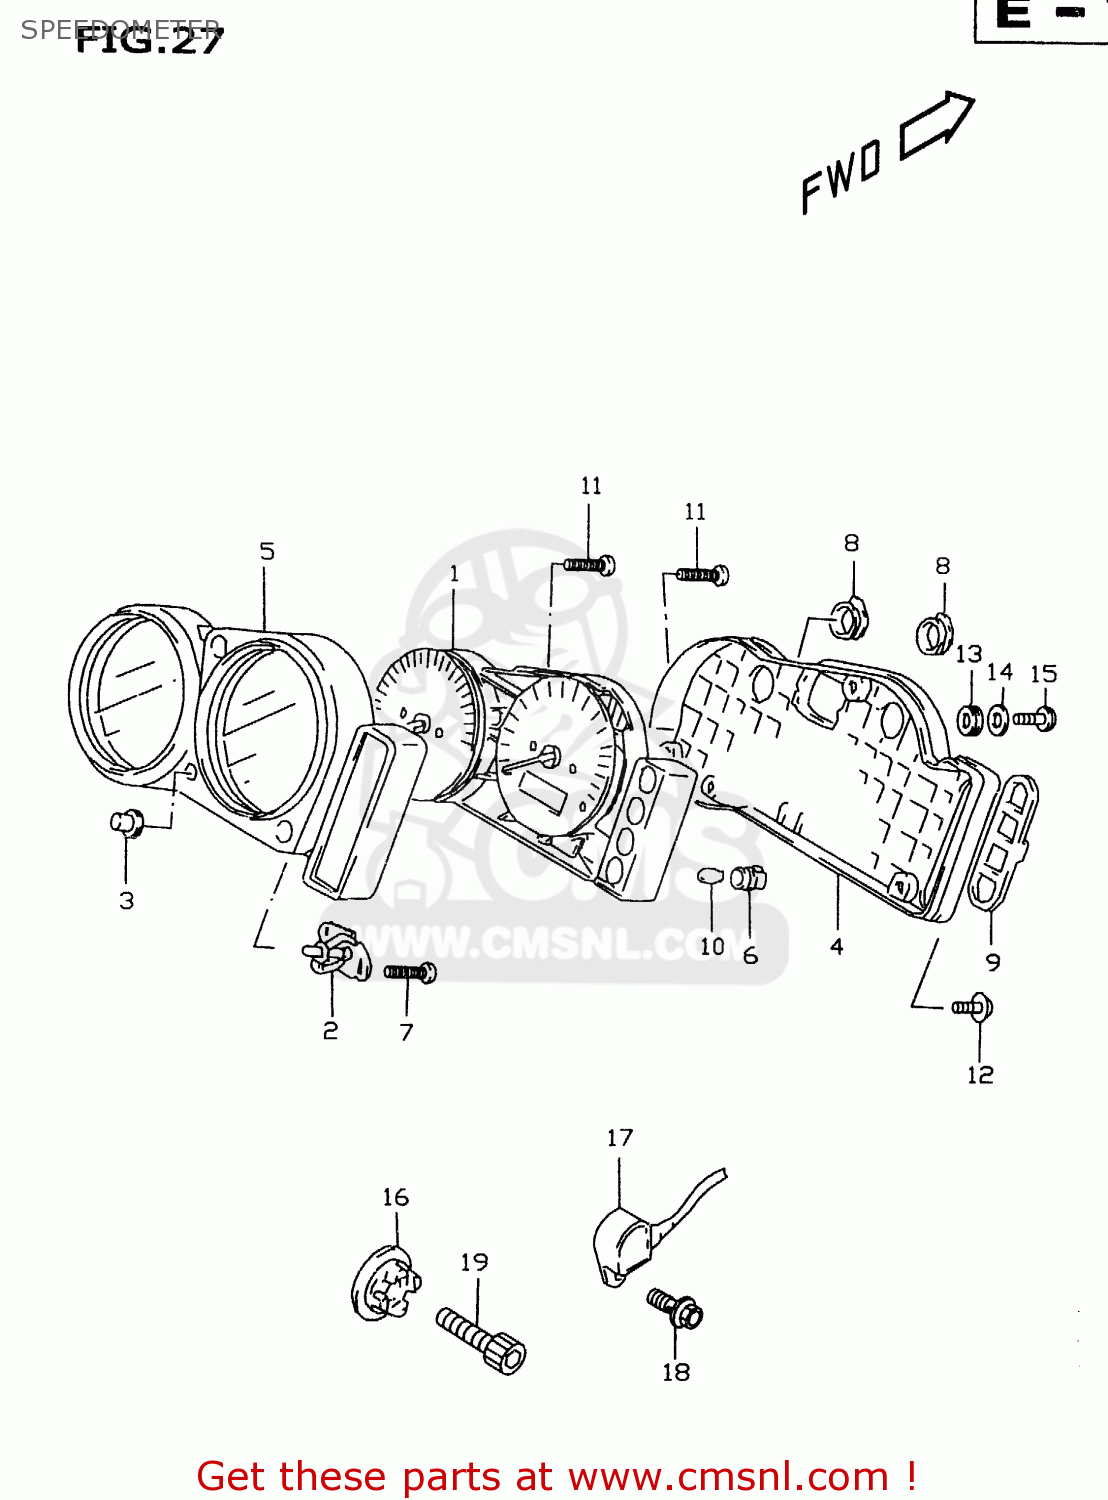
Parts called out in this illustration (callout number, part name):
1	SPEED & TACHOMETER ASSY
2	ATTACHMENT,SWITCH
3	SWITCH,GUM
4	CASE ASSY
5	VISOR
6	SOCKET(T:6.5)
7	SCREW(3X10)
8	CAP,BLIND NO.1
9	CAP,BLIND NO.2
10	BULB(12V1.7W,T6.5)
11	SCREW
12	SCREW
13	CUSHION,METER
14	WASHER(5.5X16X1.2)
15	SCREW
16	ROTOR,SPEED
17	SENSOR,SPEED
18	BOLT
19	BOLT
